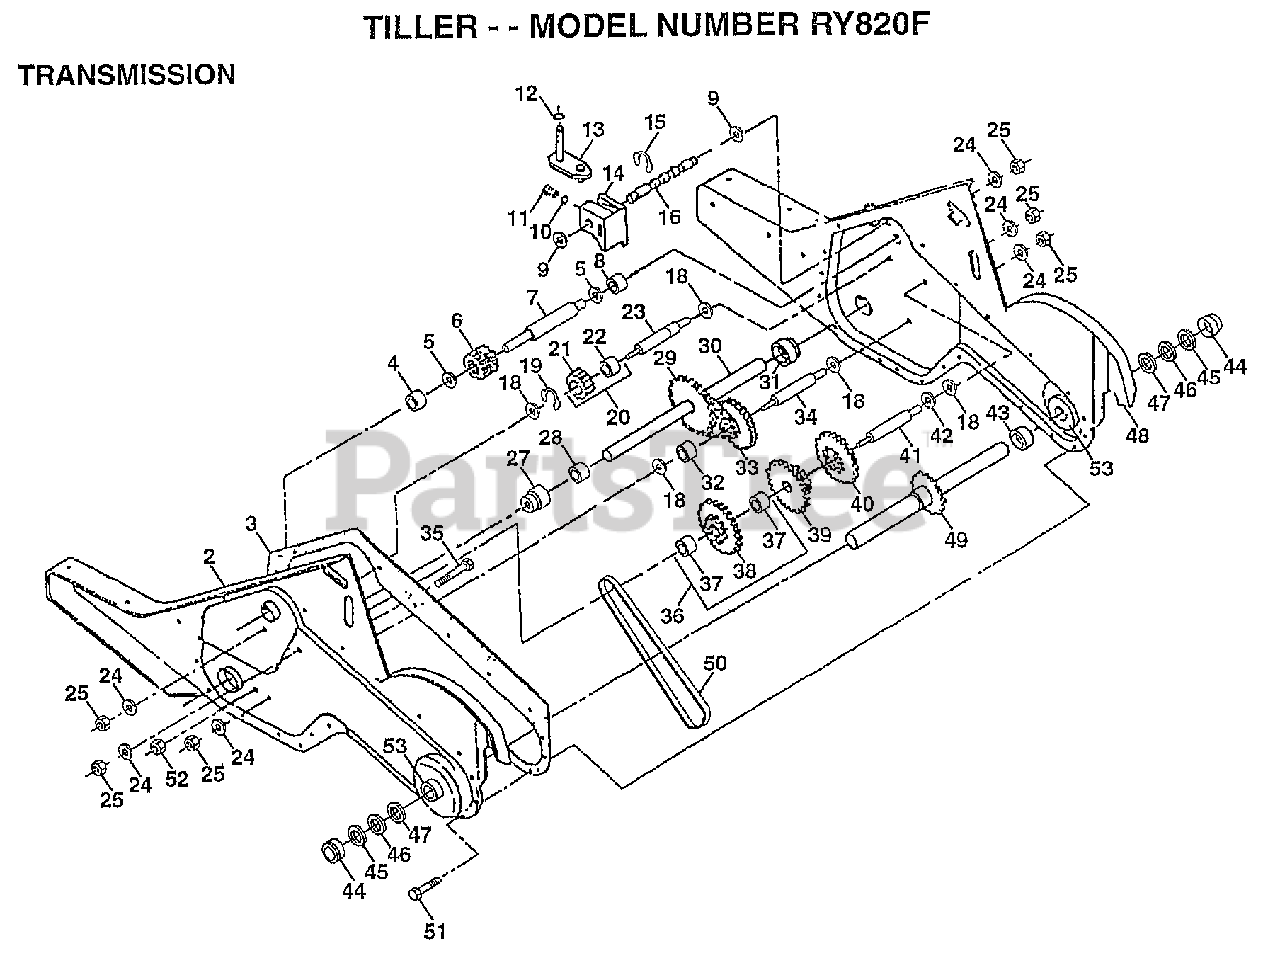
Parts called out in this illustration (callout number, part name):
2	GEARCASE LH W/BRG
3	GASKET TI
4	NEEDLE BRNG LT
5	"T, BEARING"
6	GEAR PINION INPUT
7	"SHAFT.INPUT.""D"""
8	"TI, BEARING"
9	WASHER SEAL
11	SPRING-SHIFT CRT
12	O-RING TI
13	BRACKET ASM SHIFT
14	SHIFT FORK TI
15	KLIP RING
16	SHAFT.SHIFTER
18	WASHER
19	KLIP RING
20	GEAR ASSY CRT
21	GEAR-REV IDLR CRT
22	NEEDLE BEARING TI
23	SHAFT CRT
24	LOCKWASHER
25	NUT.ASF.HEX.7/16
27	BEARING.SHAFT.LH.
28	BUSHING TI
29	CHAIN CRT
30	GROUND SHAFT ASSY
31	BEARING.SHAFT.RH.
32	SPACER TI
33	SPRCKT 8 GEAR CRT
34	SHFT 2ND RED. CRT
35	SCRW WHIZ LOK CRT
36	SPROCKET.ASM.W/BR
37	BEARING
39	GEAR TI
40	GEAR TI
41	REDUCTION SHFT TI
42	BRNG RACE
43	SPACER TI
44	CUP.FORMED.
45	RING SPIRAL CRT
46	SEAL RING RUBBER
47	OIL SEAL STD
48	GEARCASE RH W/BRG
49	TINE SHAFT
50	CHAIN.50 LINK TI
51	SCREW
52	NUT.HEX.5/16-18
